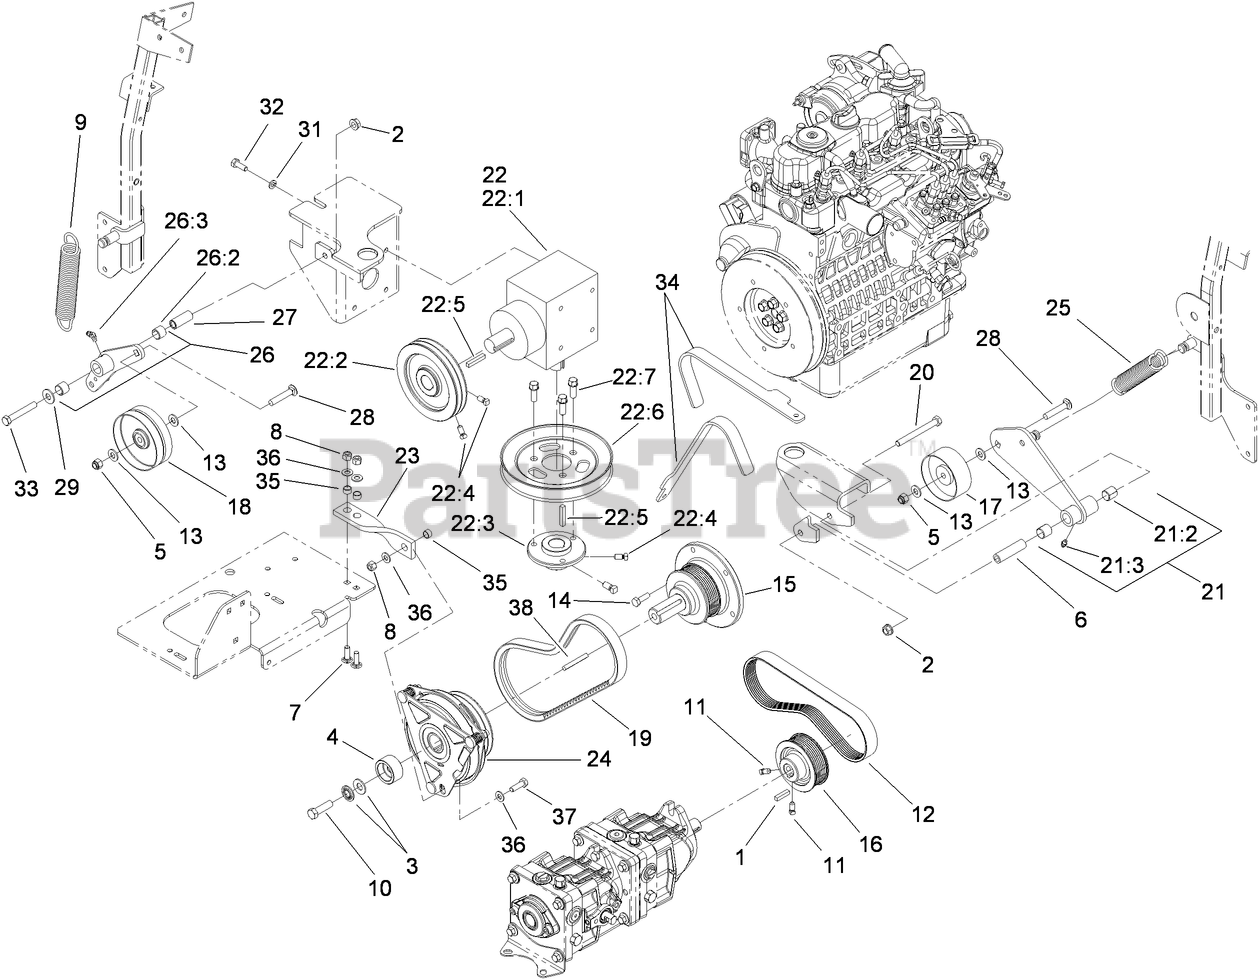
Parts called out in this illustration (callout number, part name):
2	NUT-HHF, WHIZ
3	WASHER-SPRING
4	RETAINER-CLUTCH
5	NUT-LOCK, NI
6	BUSHING-PIVOT, IDLER
7	SCREW-CARR
8	NUT-LOCK, NI
9	SPRING-EXTENSION
10	SCREW-HH
11	SCREW-SET
12	BELT-V
13	WASHER-FLAT
14	SCREW-HH
15	SHAFT-STUB
16	PULLEY
17	PULLEY-FLAT
18	PULLEY-FLAT
19	BELT-V
20	SCREW-HH
21	PUMP IDLER ARM ASM
21:2	SLEEVE-BEARING
21:3	FITTING-GREASE
22	GEARBOX
22:1	GEARBOX-90 DEG
22:2	PULLEY
22:3	HUB-PULLEY
22:4	SCREW-SET
22:5	KEY-SQUARE
22:6	PULLEY-B SECTION
22:7	SCREW-HWH
23	STRAP-STOP, CLUTCH
24	CLUTCH-MAGNETIC
25	SPRING-EXTENSION
26	GEARBOX IDLER ASM (W/BEARINGS)
26:2	SLEEVE-BEARING
26:3	FITTING-GREASE
27	BUSHING
28	SCREW-CARR
29	WASHER-FLAT
31	WASHER-LOCK
32	SCREW-HH
33	SCREW-HH
34	TOOL-ALIGNMENT, PULLEY
35	SPACER
36	WASHER-PLAIN
37	SCREW-HH
38	KEY-SQUARE
